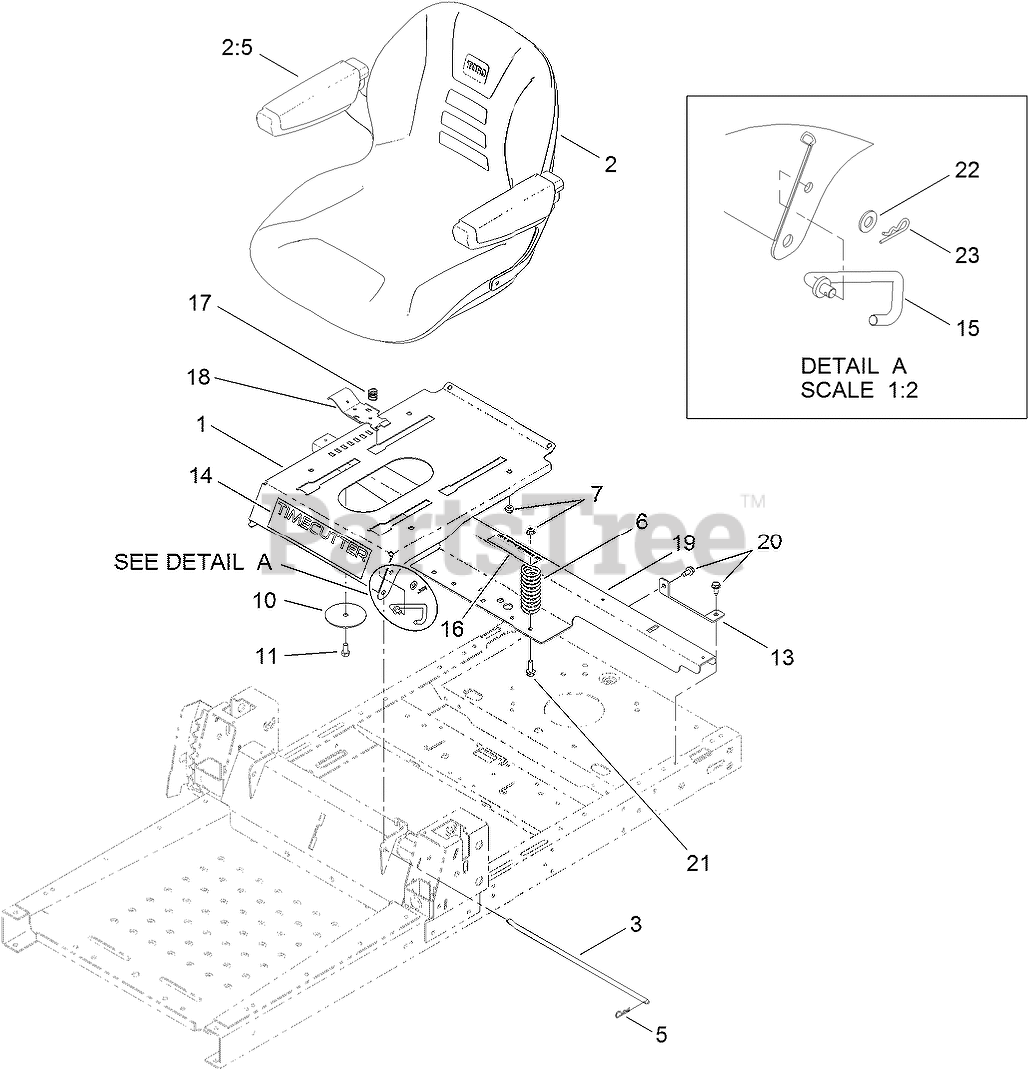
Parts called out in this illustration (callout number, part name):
1	PAN-SEAT
2	18 INCH SEAT ASM
2:5	ARMREST KIT
3	ROD-STOP
5	PIN-COTTER
6	SPRING-COMPRESSION
7	NUT-HF, NI
10	WASHER-SEAT
11	SCREW-HH
13	SUPPORT-TANK, REAR
14	DECAL-TIMECUTTER
15	STOP-SEAT
16	DECAL-SERVICE, CE
17	SPRING-COMPRESSION
18	LATCH-SEAT
19	SUPPORT-POD
20	SCREW-HWHTF
21	SCREW-HHF
22	WASHER-PLAIN
23	PIN-COTTER
